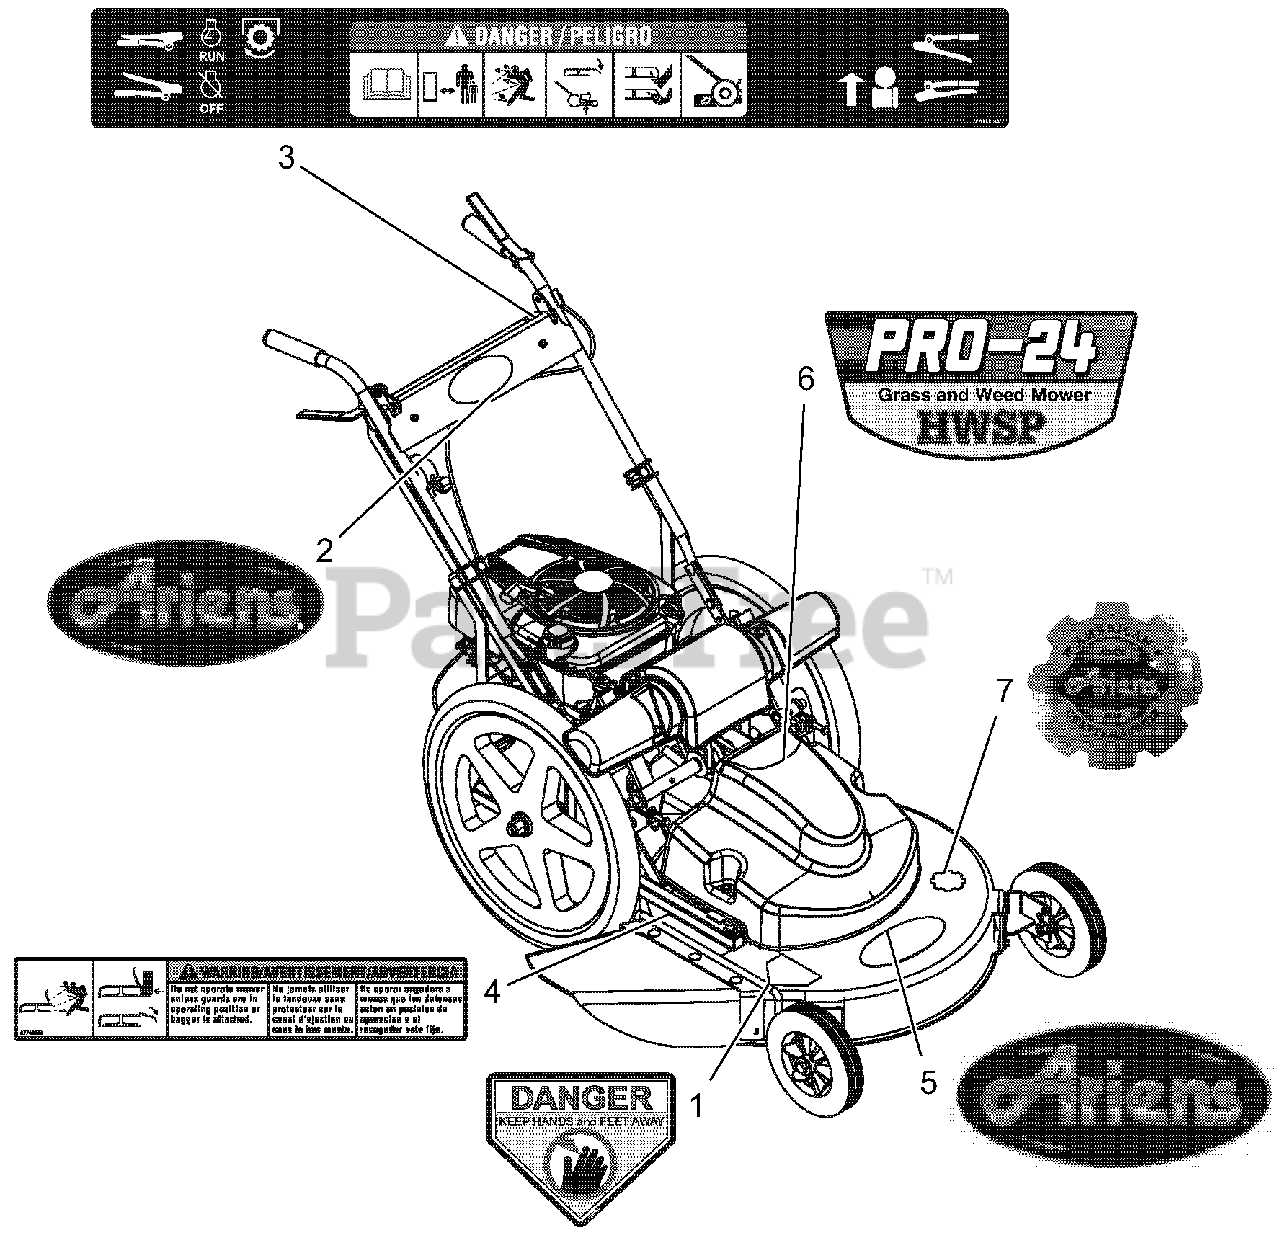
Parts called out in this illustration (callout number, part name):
1	DECAL, DANGER
2	DECAL, ARIENS JEWEL (LARGE)
3	DECAL-OPER./DANGER 24HWSP
4	DECAL, WARNING
5	DECAL, ARIENS JEWEL
6	DECAL, PRO24 HWSP ARIENS
7	DECAL, ARIENS HERITAGE-SMALL
